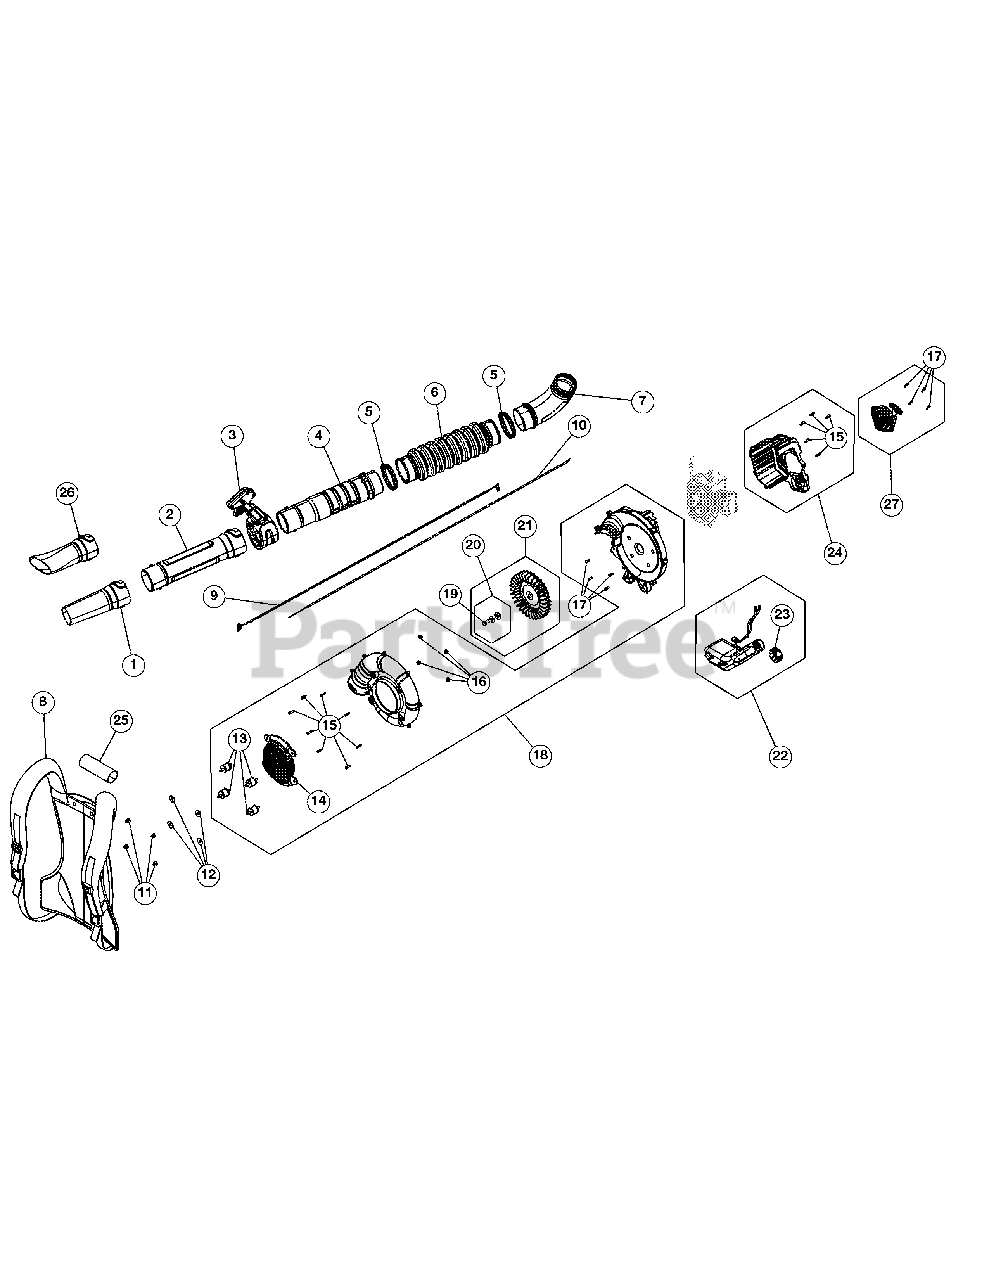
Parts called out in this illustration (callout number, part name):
1	Nozzle
2	Lower Blower Tube
3	Throttle Grip Assembly
4	Upper Blower Tube
6	Flex Tube
8	Harness
9	Lead Wire
10	Throttle Cable
11	Nut
12	Washer
13	Insulator Mount
14	Intake Cover
17	Screw
18	Impeller Housing Assembly (Incl. 13-17)
20	Impeller Hardware (Incl. 19)
21	Impeller (Incl. 19 & 20)
22	Fuel Tank Assembly (Incl. 23)
23	Fuel Cap
24	Housing Assembly (Incl. 15)
26	Flare Nozzle
27	Starter Assembly (Incl. 17)
